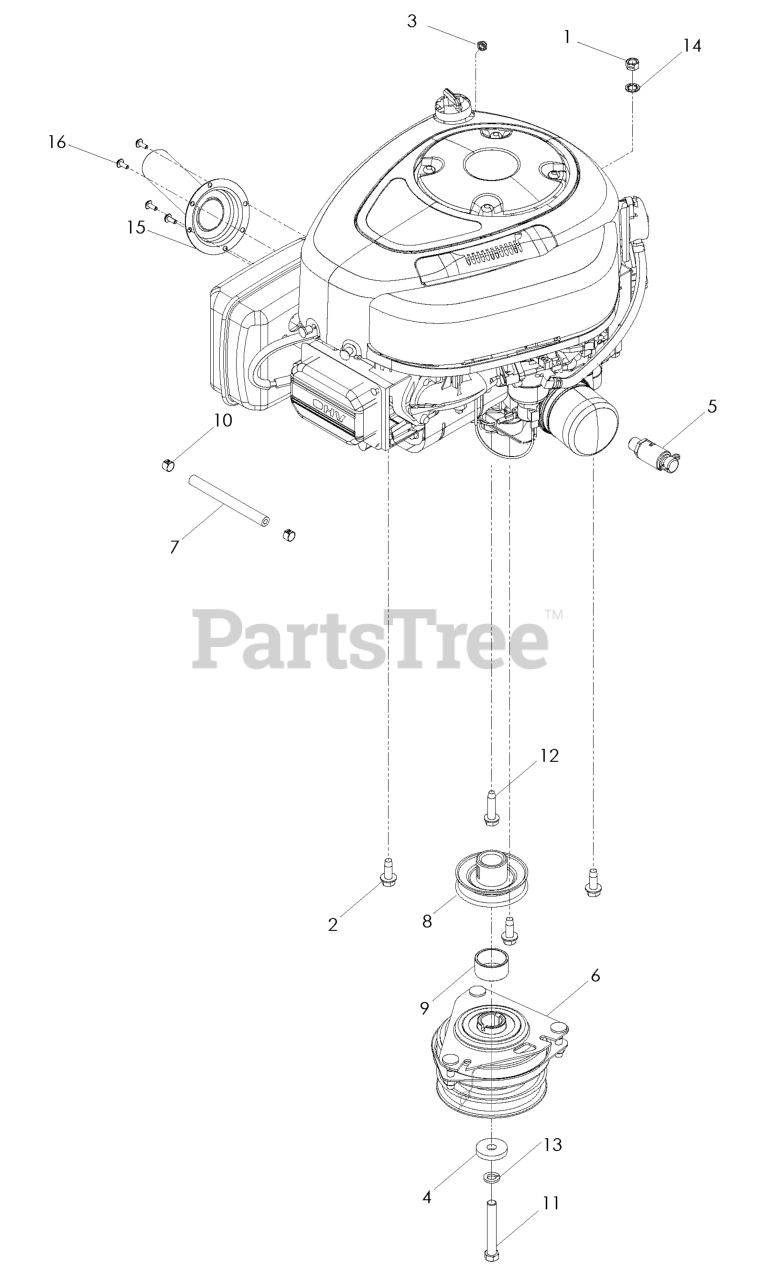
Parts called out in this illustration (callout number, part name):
1	NUT 3/8C CENTERBLOCK
2	BOLT 3/8-16 X 1.0
3	JAM NUT 1/4C (2 2 PW01)
4	CLUTCH, WASHER
5	OIL DRAIN FITTING
6	CLUTCH 90 FT/LB OGURA
7	FUEL LINE 5"
8	PULLEY, ENGINE
9	SPACER, ENGINE - PULLEY
10	HOSE CLAMP
11	HEX SCREW 7/16-20 X 3
12	BOLT 3/8-16 X 1 1/2 ZINC CLEAR
13	WASHER 7/16 LOCK
14	WASHER, 3/8 ITLW ZN
15	MUFFLER EXT.(PAINTED)
16	SCREW, TAP #10-16 X 1/2
